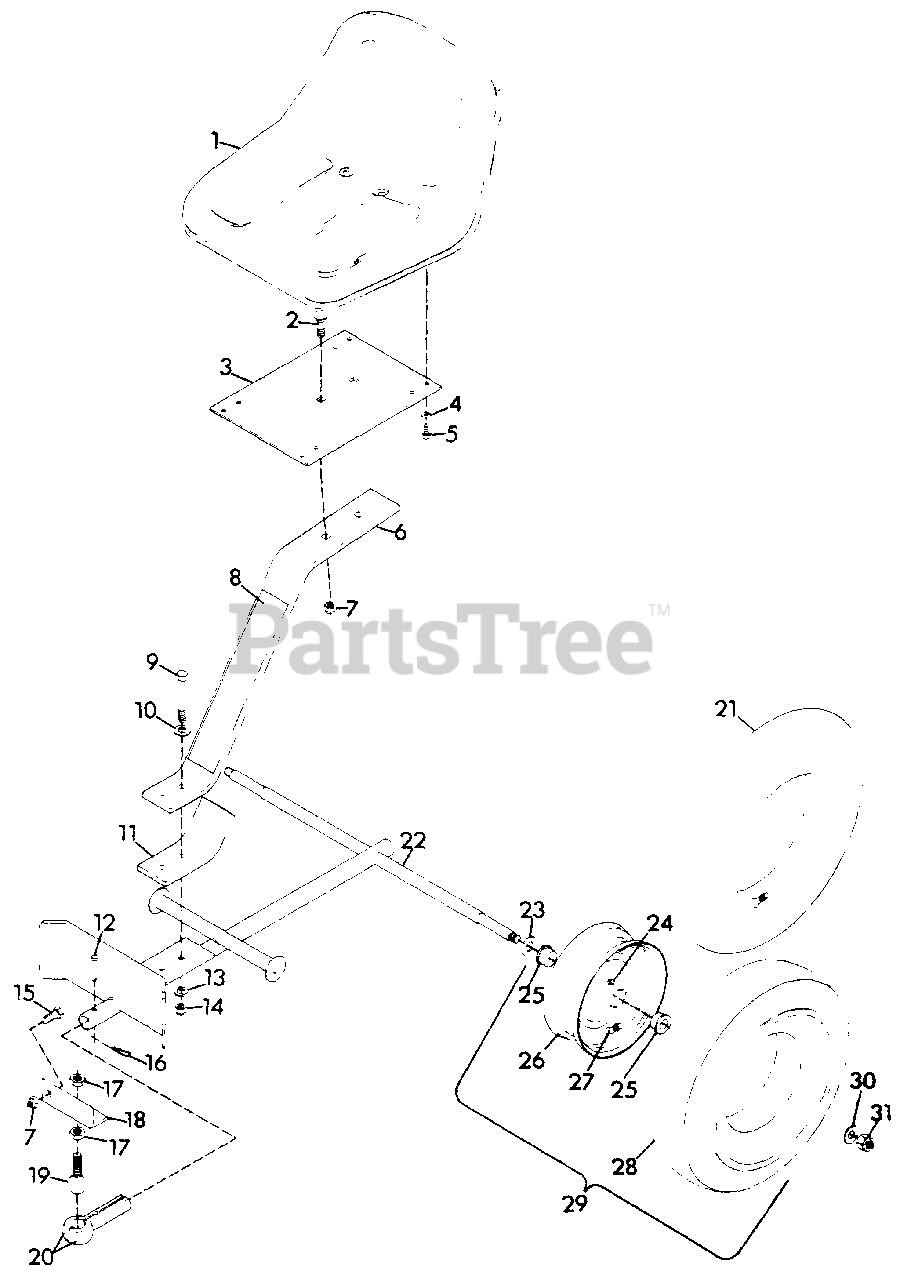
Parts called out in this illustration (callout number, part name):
1	SEAT, HIGH BACK
2	BOLT, 1/2-13X1.50 RD HD SQ NK
3	PLATE
4	WASHER, LOCK 5/16 REG.
5	BOLT, HEX 5/16-18X.75
6	ASSEMBLY, SEAT SPRING AND DECAL
7	NUT, LOCK 1/2-13
8	DECAL, WARNING
9	BOLT, HEX 1/2-13X3.50
10	WASHER, FLAT .563X1.375X.109
11	PLATE, REINFORCEMENT
12	PIN, DRAW BAR
13	WASHER, LOCK 1/2-13 REG.
14	NUT, JAM 1/2-13 HEX
15	BOLT, HEX 1/2-13X1.25
16	PIN, COTTER HAIR
17	NUT, JAM 5/8-18
18	BRACKET
19	STUD, BALL
20	SOCKET, SPLIT
21	TUBE
22	WELDMENT, FRAME
23	WASHER, FLAT .812X1.496X.134
24	FITTING, LUBE 1/4-28
25	BUSHING, WHEEL
26	WHEEL, ASSEMBLY LESS TIRE/TUBE
27	ASSEMBLY, VALVE STEM
28	TIRE
29	WHEEL, SULKY ASSEMBLY COMPLETE(INCLUDES ITEM NOS. 24,25,26,27,28)
30	WASHER, FLAT.656X1.312X.095
31	NUT, LOCK 5/8-18 L.T.
